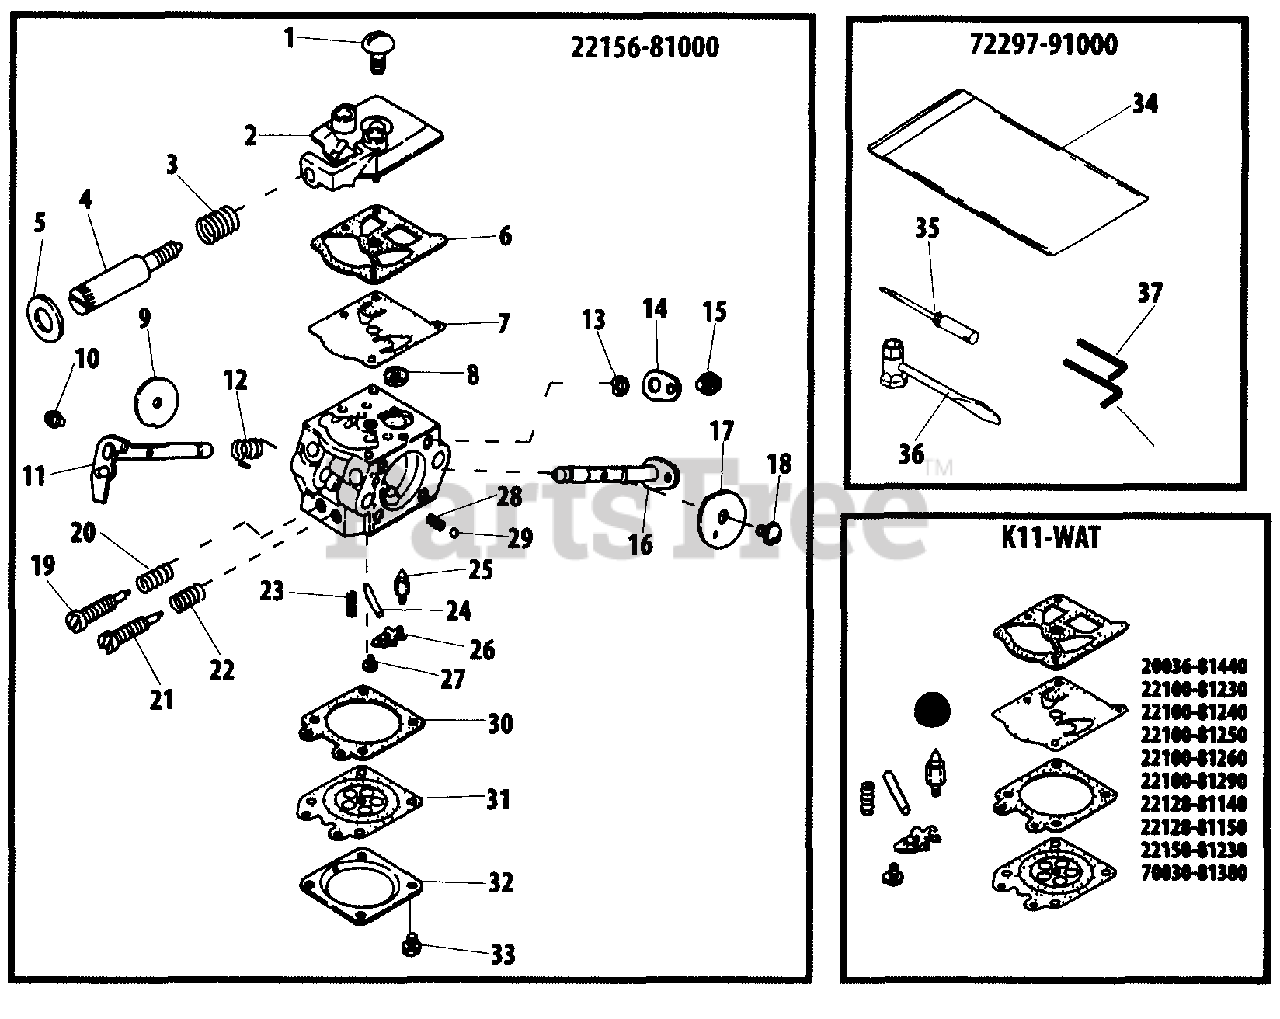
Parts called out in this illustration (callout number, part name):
1	SCREW, PUMP COVER
2	COVER, PUMP
3	SPRING
4	SCREW, IDLE ADJUST
5	SEAL
6	GASKET, PUMP
7	DIAPHRAGM, PUMP
8	STRAINER
9	VALVE, THROTTLE
10	SCREW
11	SHAFT, THROTTLE
12	SPRING, RETURN
13	RING, RETAINING
14	TRIGGER, THROTTLE
15	SCREW
16	SHAFT, CHOKE
17	VALVE, CHOKE
18	SCREW
19	NEEDLE - LOW SPEED
20	SPRING
21	NEEDLE - HIGH SPEED
22	SPRING
23	SPRING, METERING LEVER
24	PIN, METERING LEVER
25	VALVE, INLET NEEDLE
26	LEVER, METERING
27	SCREW, METERING LEVER PIN
28	SPRING, CHOKE
29	BALL, CHOKE
30	GASKET, METERING
31	DIAPHRAGM, METERING
32	COVER, DIAPHRAGM
33	SCREW
34	BAG, TOOL
35	SCREWDRIVER
36	T-WRENCH
37	HEX KEY - 3mm
22156-81000	CARBURETOR
72297-91000	TOOL KIT
K11-WAT	REPAIR KIT
